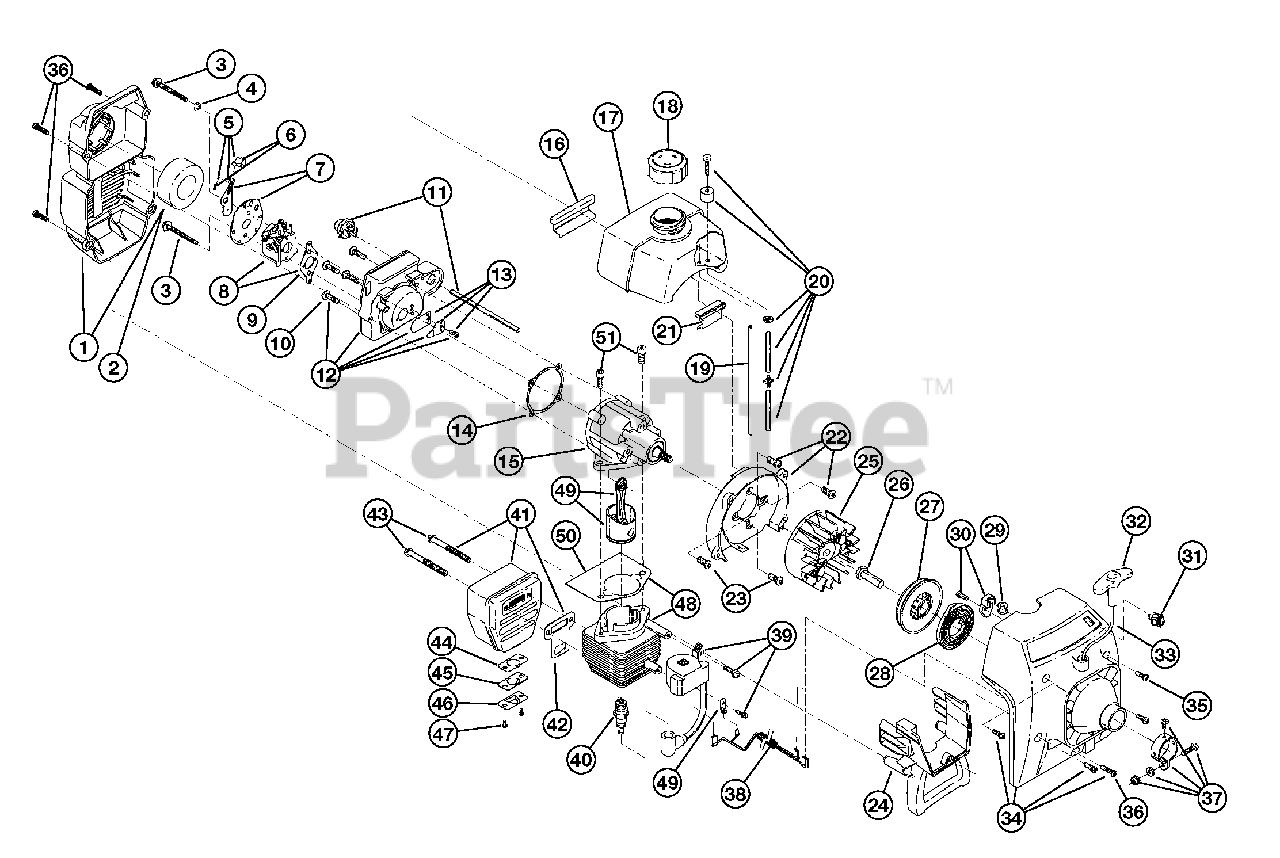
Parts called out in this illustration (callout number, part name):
1	Air Cleaner/Muffler Cover Assembly
2	Air Cleaner Filter
3	Carburetor Mounting Screws
4	Wavey Washer
5	Choke Lever Assembly
6	Choke Knob & Screw
7	Choke Lever & Plate
8	Carburetor Assembly
9	Carburetor Gasket
10	Carb Mount Screw
11	Primer and Hose Assembly
12	Carburetor Mount Assembly
13	Reed Assembly
14	Carburetor Mount Gasket
15	Crankcase Service Assembly
16	Rear Mounting Pad
17	Fuel Tank Assembly
18	Fuel Cap Assembly
19	Fuel Return Line
20	Fuel Line Assembly
21	Front Mounting Pad
22	Shroud Assembly
23	Shroud Screw
24	Shroud Extension and Stand
25	Flywheel Assembly
26	Square Nut Drive
27	Recoil Pulley
28	Recoil Spring
29	Rope Guide
30	Pulley Retainer Assembly
31	Switch Assembly
32	Pull Handle
34	Starter Housing Assembly
35	Housing Screw
36	Cover Screw
37	Upper Clamp Assembly
38	Wire Lead
39	Module Assembly
40	Spark Plug
41	Muffler Assembly
42	Exhaust Gasket
43	Muffler Mounting Bolt Assembly
44	Spark Arrestor
45	Spark Arrestor Plate
46	Spark Arrestor Hood
47	Spark Arrestor Screw
48	Cylinder Assembly
49	Piston and Rod Assembly
50	Cylinder Gasket
51	Cylinder Bolt
52	Ground Tab
